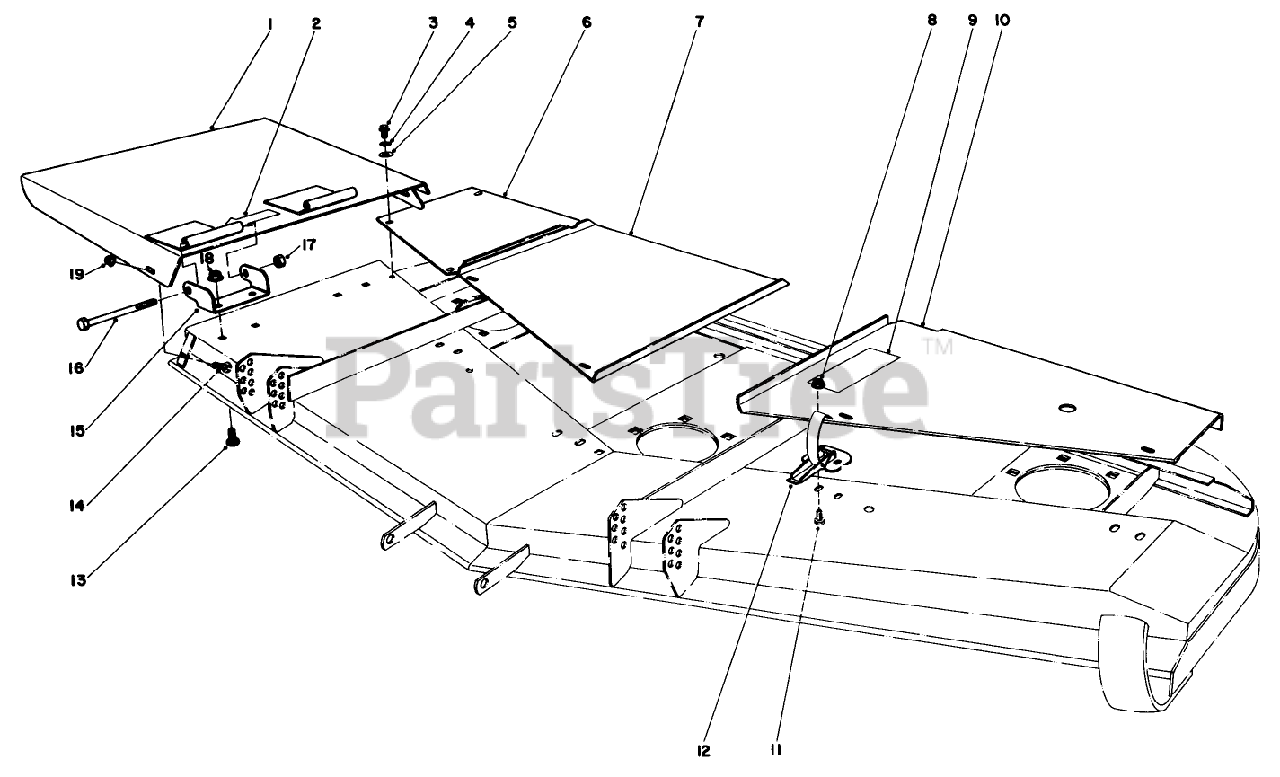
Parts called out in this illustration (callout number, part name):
4	SCREW-HH
5	WASHER-FLAT
7	CTR DECK COVER *R
8	NUT-LOCK, FLANGE
11	SCREW-SHWH
12	CLAMP-SLOTTED
13	SCREW-CARR
16	SCREW-HH
17	NUT-HEX
18	NUT-HHF, WHIZ
19	NUT-HF
